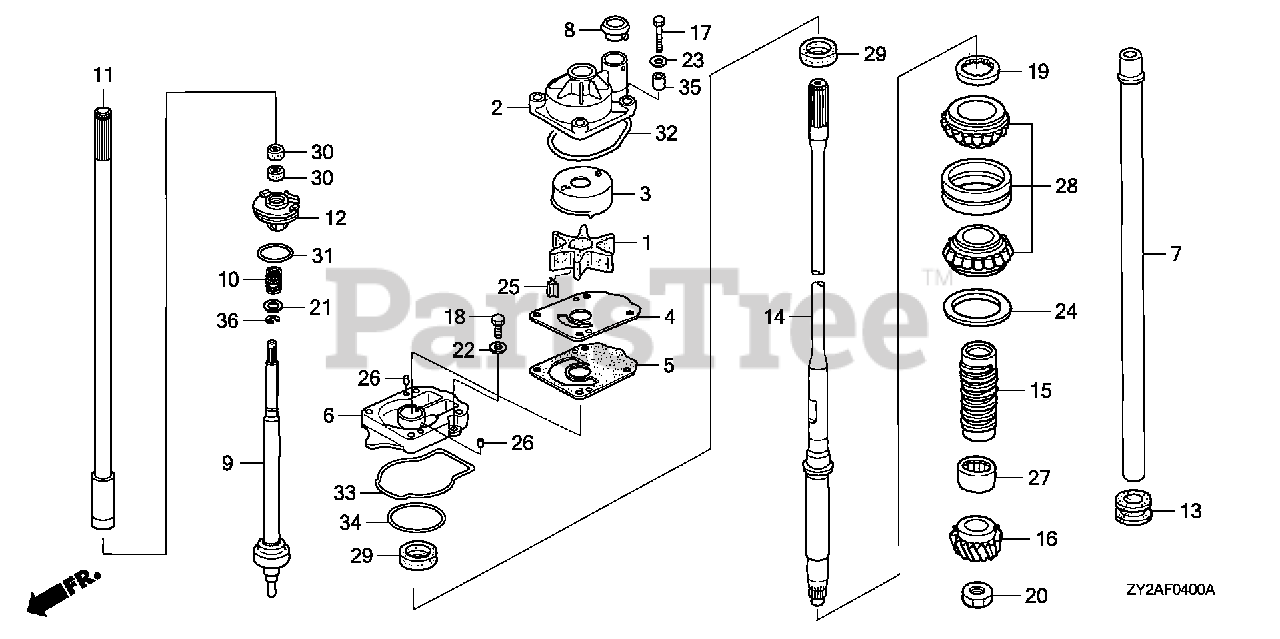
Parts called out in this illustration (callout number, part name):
1	IMPELLER, PUMP
2	HOUSING, IMPELLER
3	LINER, PUMP
4	COVER, IMPELLER
5	GASKET B, IMPELLER
6	HOUSING, WATER PUMP
7	TUBE, WATER (XL)
8	RING, WATER TUBE SEAL
9	ROD, SHIFT
10	SPRING, SHIFT ROD
11	ROD A, SHIFT (XL)
12	HOLDER, SHIFT ROD
13	GROMMET, EXTENSION CASE
14	SHAFT, VERTICAL (XL)
15	SLINGER, OIL
16	GEAR, PINION
17	BOLT, HEX. (8X60)
18	BOLT, HEX. (6X16)
19	NUT, LOCK (64MM)
20	NUT, HEX. (18MM)
21	WASHER, PLAIN (12MM)
22	WASHER, PLAIN (6MM)
23	WASHER (8MM)
24	SHIM A, GEAR (0.10)
24	SHIM B, GEAR (0.15)
24	SHIM C, GEAR (0.30)
24	SHIM D, GEAR (0.50)
25	KEY, WOODRUFF
26	PIN, DOWEL (6X10)
27	BEARING, NEEDLE (32X46X37)
28	BEARING, TAPER ROLLER (30X62X40)
29	SEAL, WATER (26X42X7)
30	SEAL, WATER (12X21X6)
32	O-RING, WATER PUMP
33	O-RING, WATER PUMP HOUSING
34	O-RING (69.1X2.4)
35	COLLAR, DISTANCE
36	E-RING (10MM)
